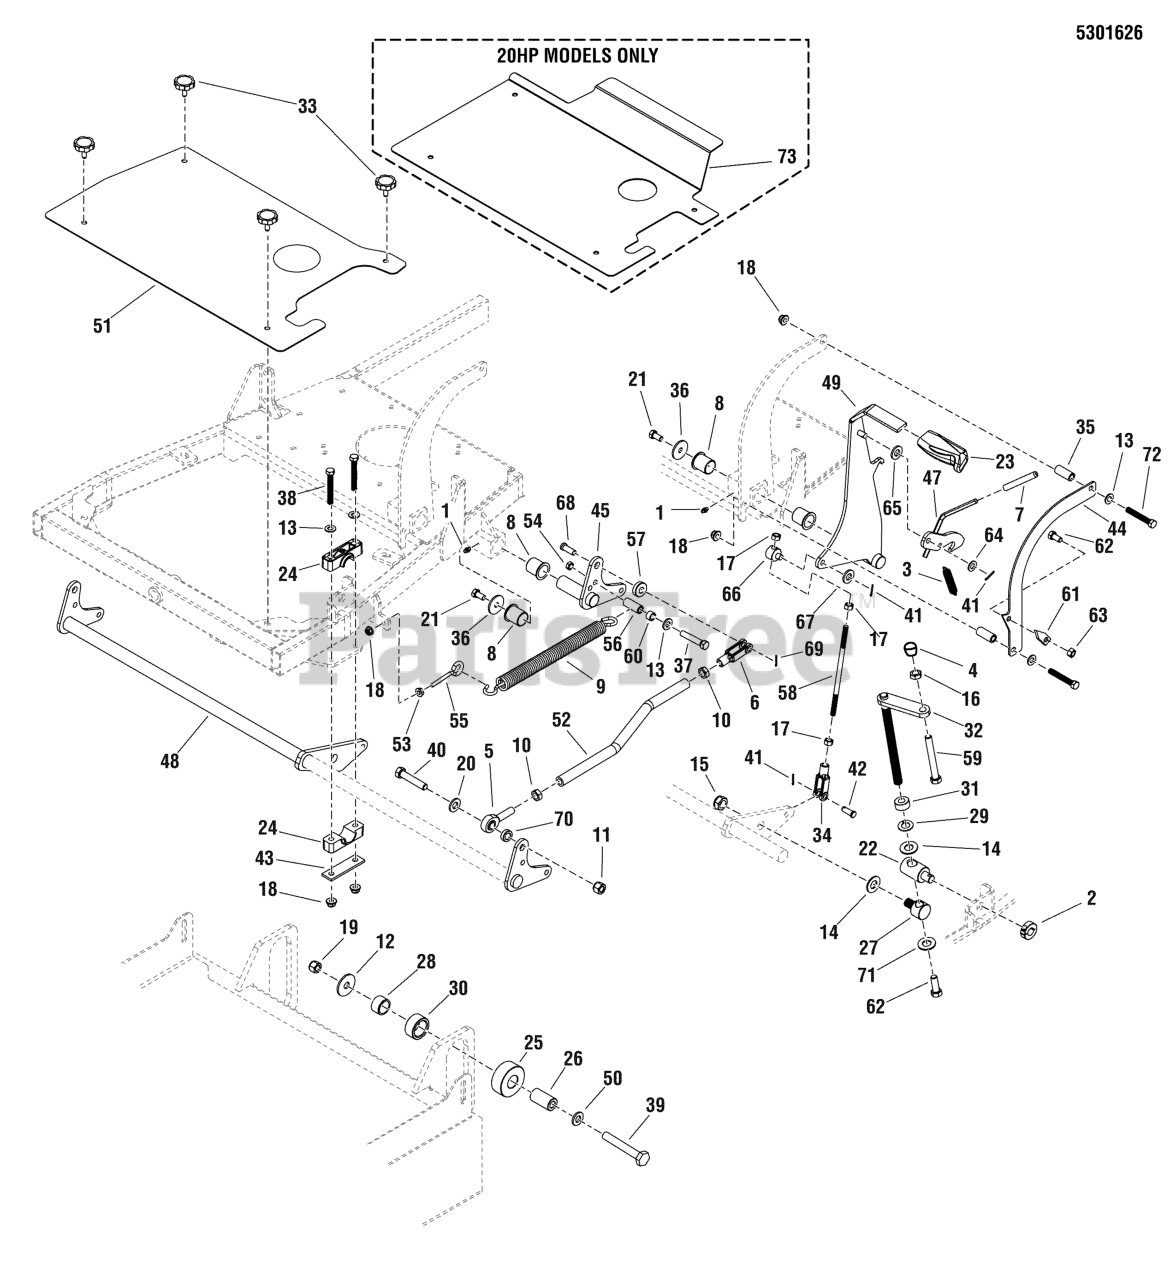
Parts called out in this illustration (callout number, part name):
1	GREASE FITTING, 1/4-28 STRAIGHT
2	COLLAR, 5/8 SPLIT
3	SPRING, EXTENSION
4	KNOB, PLASTIC, 1/2-13
5	BALL JOINT, 1/2-20, MALE
6	CLEVIS, 1/2-20, STEEL
7	COVER, VINYL HANDLE
8	BUSHING, 1.00 X 1.13 X 1.38, PLASTIC
9	SPRING, DECK LIFT ASSIST
10	NUT, 1/2-20 HEX JAM
11	NUT, Hex, Nylon Lock, 1/2-20
12	WASHER, 1/2 USS
13	WASHER, 3/8 SAE
14	WASHER, 5/8 SAE
15	NUT, 5/8-11 HEX JAM NYLON LOCK
16	NUT, 1/2-13 HEX JAM
17	NUT, 3/8-24 HEX JAM
18	NUT, 3/8-16 HEX NYLOCK FLANGE
19	NUT, Hex Flange, Nylock, 1/2-13
20	WASHER, 1/2 GD9 YZ
21	BOLT, 3/8-16 X 3/4, PLT W/PATCH
22	PIVOT, SPRING ROD
23	GRIP, BLACK FLEXIBLE
24	PIVOT BLOCK, PLASTIC
25	GUIDE, DECK - TWR
26	SPACER, .52 X 1.00 X 1.88 - SS
27	PIVOT, DECK LIFT
28	BUSHING, SLEEVE, 1.00 X 1.25 X .75
29	WASHER, THRUST, .63 X 1.13 X .06
30	ROLLER, 1.256 X 1.75 X .813
31	SPACER, .64 X 1.13 X .63
32	HANDLE, CRANK, COMPACT RIDER
33	KNOB, 5/16-18 X 1.00, ROSETTE, BLK
34	CLEVIS, 3/8-24 RH, 3/8" PIN HOLE
35	SPACER, .39 X .63 X 1.00, YZ
36	WASHER, .390 X 1.38 X .109, YZ
37	BOLT, 3/8-16 X 2-1/2" GD5 CZ
38	BOLT, 3/8-16 X 2-3/4" GD5 CZ
39	BOLT, 1/2-13 X 3" GD5 CZ
40	BOLT, 1/2-20 X 2-1/2" GD5 CZ
41	PIN, 3/32 X 0.750, COT, ZINC/CLEAR
42	PIN, CLEVIS, 3/8 X 1-1/8
43	PLATE, PIVOT BLOCK SUPPORT - BLK
44	PLATE, OUTER TRANSPORT BRACKET - RED
45	WELD, BOOMER, LH - RED
46	WELD, BOOMER, RH - RED
47	WELD, DECK LOCK - RED
48	WELD, DECK LIFT SHAFT, 48 - RED
49	WELD, DECK LIFT HANDLE - RED
50	WASHER, 1/2 SAE
52	ROD, DECK LIFT, EVOLUTION 48"
53	NUT, 3/8-16 HEX SERRATED FLANGE
54	NUT, 3/8-16 HEX SIDE LOCK
55	EYE BOLT, 3/8-16 X 5, 2.88THRD, 1EYE, CZ
56	SPACER, .38 X .75 X 1.25, YZ
57	SPACER, .52 X 1.00 X .22, PM, CZ
58	ROD, LEVER CONNECTING
59	BOLT, 1/2-13 X 6 GD5 YZ
60	SPACER, .38 X .50 X .27
61	POINTER, DECK HEIGHT
62	BOLT, 1/4-20 X 3/4 GD5 YZ
63	NUT, 1/4-20 HEX NYLOCK FLANGE
64	WASHER,WAVE,M10
65	WASHER, 3/8 GD.9 FLAT
66	ADJUSTER, BRAKE LINKAGE
67	SHIM, .375 X .625 X .031 THK
68	CLEVIS PIN, 1/2 X 1.36 SAE STANDARD
69	PIN, COTTER, 1/8 X 3/4
70	SPACER, .52 X 1.00 X .44
71	WASHER, 1/4 SAE
72	BOLT, 3/8-16 X 2, GD5, CZ
73	PLATE, GUARD TOP, 2048 - RED
